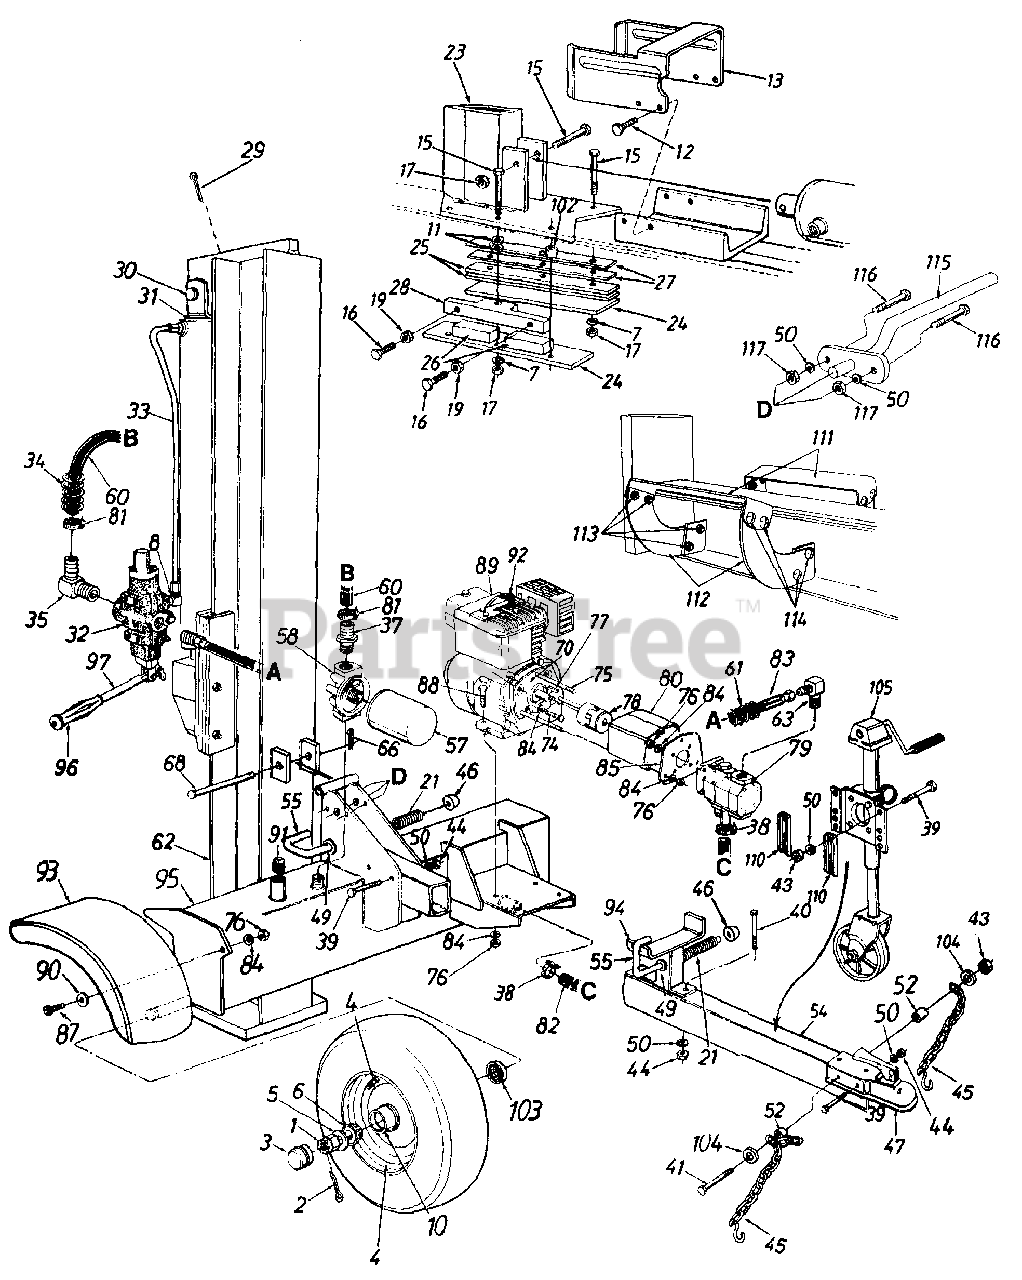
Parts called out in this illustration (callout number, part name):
1	Slotted Nut 3/4-16 Thd.
2	Cotter Pin 5/32" Dia.
5	Fl-Wash. .76" I.D. x 1.5" O.D.
6	Bearing Cone
7	L-Wash. 1/2" I.D.
8	90° Solid Male Adapter
10	Bearing Cup
11	Fl-Wash. .531" I.D. x .94" O.D.
12	Hex Cap Scr. 3/8-16 x 1" Lg.
15	Hex Bolt 1/2-20 x 2.75" Lg. (Grade 8)
16	Hex Bolt 3/8-24 x 1.5" Lg.
17	Hex L-Nut 1/2-20 Thd.
19	Hex Jam Nut 3/8-24 Thd. (Grade 5)
21	Comp. Spring 4" Lg.
23	Wedge Ass'y.
26	Adjustable Gib
29	Cotter Pin
30	Cylinder Mounting Pin
31	Hydraulic Cylinder
33	Metal Pressure Tube
34	Hose Guard
35	Return Elbow
37	3/4" Hose Barb.
38	Hose Clamp 1.5" O.D.
39	Hex Bolt 3/8-16 x 3" Lg. (Grade 8)
40	Hex Bolt 3/8-16 x 4.75" Lg.
41	Hex Bolt 3/8-16 x 4.25" Lg.
43	Hex Lock Nut
44	Lock Nut 3/8-16 (585)
45	Chain - Tow Hitch
47	Hitch Coupler
49	Fl-Wash. .635" I.D. x .93" O.D.
50	L-Wash. 3/8" I.D.
52	Spacer .445" Lg.
54	Tongue Tube
55	Locking Rod
57	Filter Element
58	Filter Head
60	Return Hose 3/4" I.D. x 44" Lg.
61	Hose Guard
62	Vertical Beam Weldment
63	90 degree Adapter (Male)
66	Cotter Pin 1/8" Dia.
68	Hinge Pin 1/2 x 4.8" Lg.
74	Hex Bolt 5/16-24 x .62" Lg.
75	Hex Bolt 5/16-24 x 5.25" Lg.
76	Hex Nut 5/16-24 Thd.
77	Sq.-Key 1/4" x 2" Lg.
78	Flexible Coupling
79	Gear Pump
80	Coupling Shield
81	Hose Clamp 5/8"
82	Suction Hose 1" I.D.
83	High Pressure Hydraulic Hose
84	L-Wash. 5/16" I.D.
87	Hex Bolt 5/16-24 x .75" Lg.
88	Hex Bolt 5/16-24 x 1.75" Lg.
89	Engine
90	Fl-Wash. .344" I.D. x .875" O.D.
91	L-Vent Pipe Plug
92	Spark Plug Boot
95	Frame Weldment
96	Grip
97	Control Handle
102	Spacer 1/2" I.D. x .86" Lg.
103	Bearing Seal Only
104	Fl-Wash. 3/8" I.D. x .87" O.D.
105	Jack Stand
112	Cradle Support Brkt.
113	Flanged Lock Nut 3/8-16 Thd.
114	Carriage Bolt 3/8-16 x 1" Lg.
117	Hex Nut 3/8-16 Thd.
